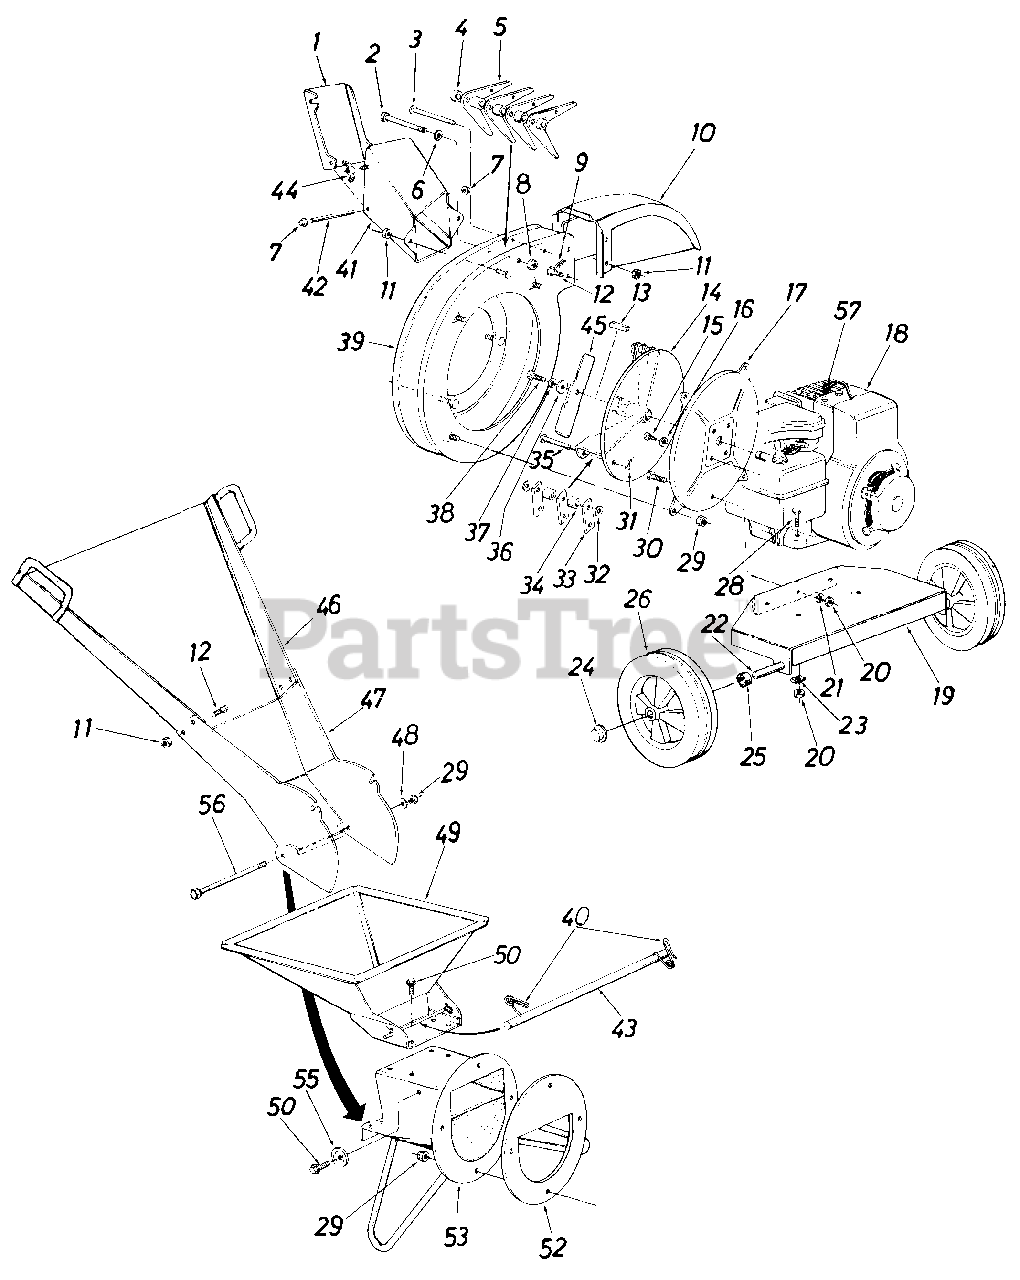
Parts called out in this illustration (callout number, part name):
1	Door Chip It
2	Hex Bolt 1/2-20 x 4.50" Lg.
3	Clevis Pin
4	Flail Spacer 7/32" Lg.
5	Cutting Finger
6	L-Wash. 1/2" I.D.
7	Palnut 3/16" Dia.
8	Hex Jam Nut 1/2 20 Thd.
9	Cotter Pin 3/32" Dia. x 3/4" Lg.
10	Chute Deflector
11	L.-Nut 1/4-20 Thd.
12	Hex Bolt 1/4-20 x .50" Lg.
13	Sq. Key 1/4" x 2.00" Lg.
14	Impeller Assembly
15	Hex Bolt 5/16-24 x 3/4" Lg.
16	L.-Wash. 5/16" I.D.
17	Hopper to Engine Mtg. Plate
18	Engine
19	Engine Mounting Plate
20	Hex Nut 5/16-24 Thd.
21	L.-Wash. 5/16" I.D.
22	Shaft
23	Special L.-Wash. 5/16" I.D.
24	Push Cap
25	Spacer
26	Wheel Ass'y.-Comp.
28	Hex Bolt 5/16-24 x 1.50" Lg.
29	Elastic Lock Nut 5/16-18 Thd.
30	Hex Bolt 5/16-24 x .62" Lg.
31	Cotter Pin 1/8" Dia. x 1.00" Lg.*
32	Fl.-Wash. .531" I.D. x 937 O.D. x .09
33	Flail
34	Flail Spacer 23/32" Lg.
35	Clevis Pin .50" Dia. x 3.0" Lg.
36	Fl.-Wash. .406" I.D. x 1.25" O.D. Hdn.
37	L.-Wash. 3/8" I.D. H.D.
38	Hex Bolt 3/8 24 x 2.0" Lg. H.T.
41	Chip-lt Guide Ass'y.
42	Hinge Pin
43	Release Bar
44	Wing Nut Elastic 1/4-20 Thd.
47	Lower Leaf Ramp Section
48	Fl.-Wash. 5/16" I.D.
49	Hopper Assembly
50	Hex Wash. Hd. Self-Tap Scr. 5/16-18 x .75" Lg.
52	Back-Up Plate
53	Inlet Guide Assembly
55	Stop Washer
56	Hex Bolt 5/16-18 x 8.38" Lg.
57	Spark Plug Boot
